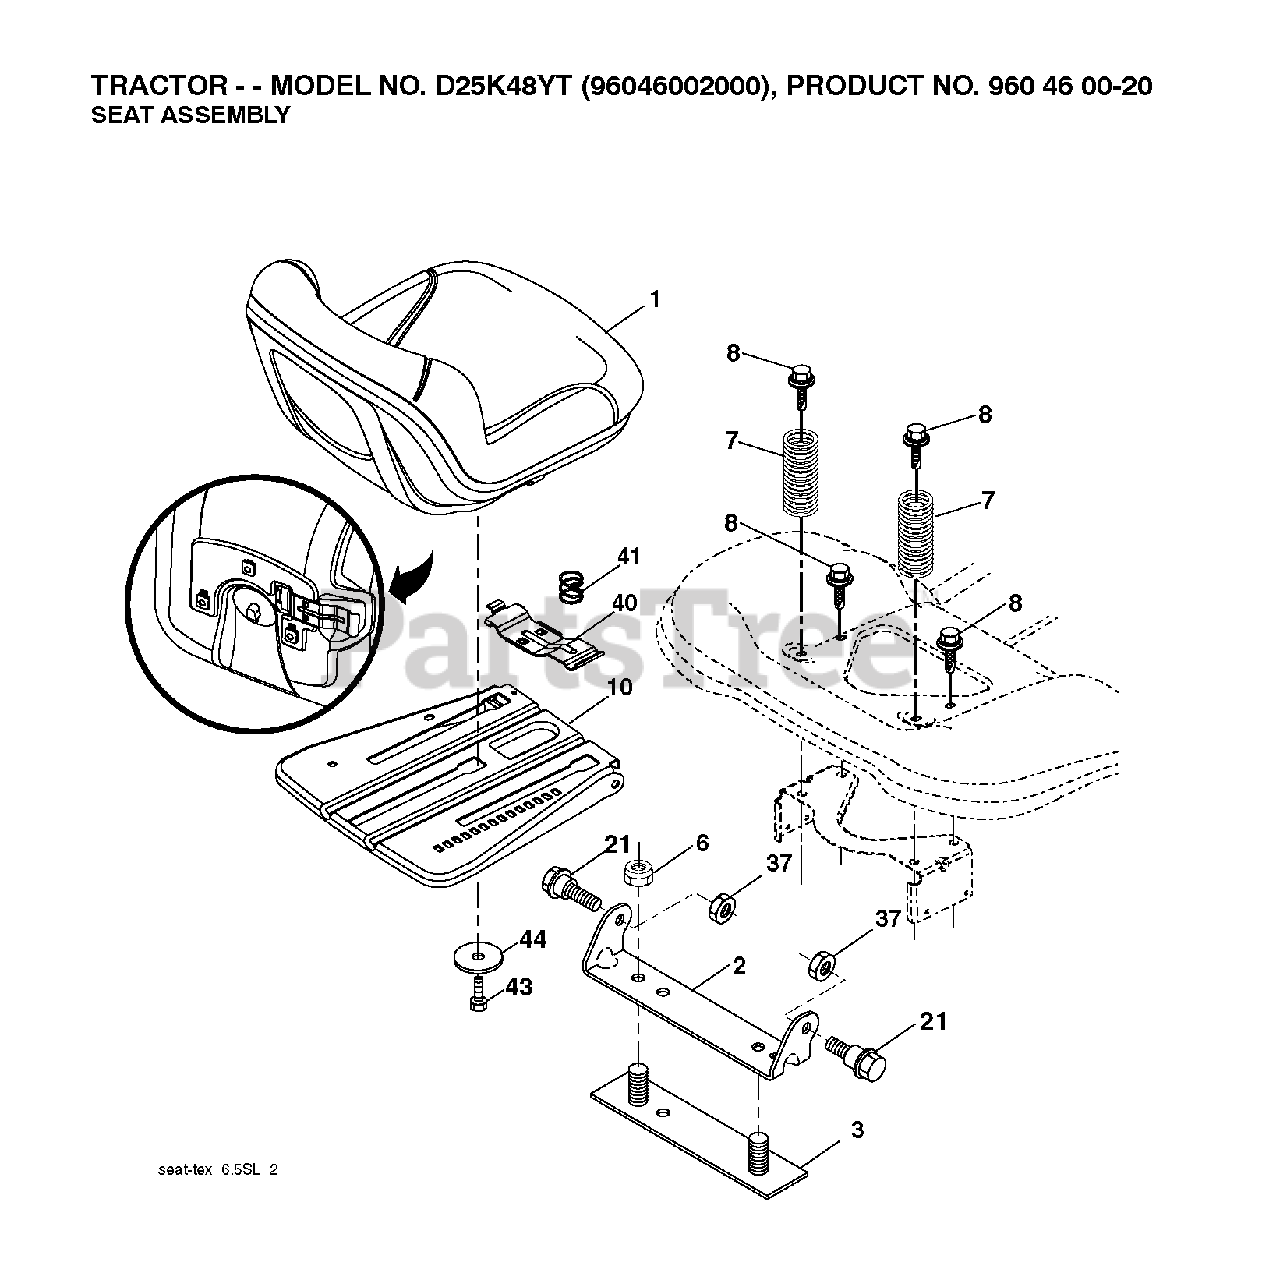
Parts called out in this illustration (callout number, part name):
1	SEAT.TG150.BLK.NLOGO.
2	BRKT.PIVOT.FENDER
3	STRAP
6	NUT
7	SPRING COMPRESSION
8	BOLT, 5/16-18 X 1 3/4
10	PAN.ASM.SEAT.3PT
21	BOLT.SHOULDER.5/16-18
37	NUT.71038.31-18.HEX.NYLOCK
40	HANDLE.SLIDE.SEAT.TEX.BLACK
41	SPRING.LATCH.SEAT.TEX
44	WASHER 13/32 X 2-3/8 X 12GA
